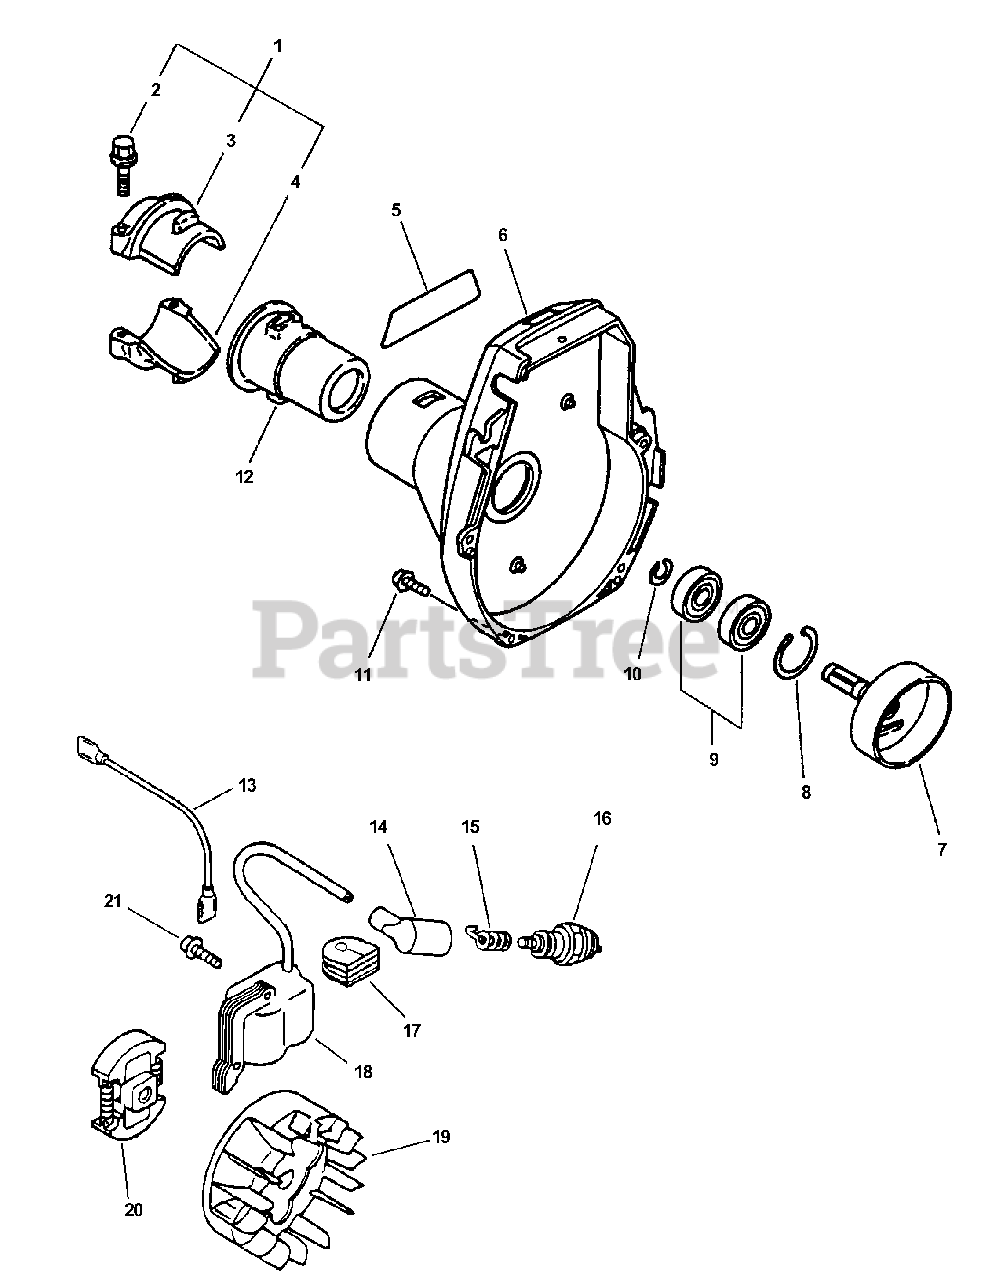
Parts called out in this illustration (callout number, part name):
1	MAIN PIPE CLAMP KIT
2	BOLT - 5X25
3	CLAMP, MAIN PIPE - UPPER
4	CLAMP, MAIN PIPE - LOWER
5	LABEL - MODEL PAS-211
6	CASE, FAN
7	DRUM, CLUTCH
8	RING, RETAINING - 28
9	BEARING, BALL - 6001
10	RING, RETAINING - 12
11	SCREW - 4X16
13	LEAD - IGNITION
14	CAP, SPARK PLUG
15	TERMINAL, SPARK PLUG CAP
16	SPARK PLUG -- BPM-7A
18	COIL, IGNITION
19	FLYWHEEL
20	CLUTCH ASSY
21	SCREW - 4X22
